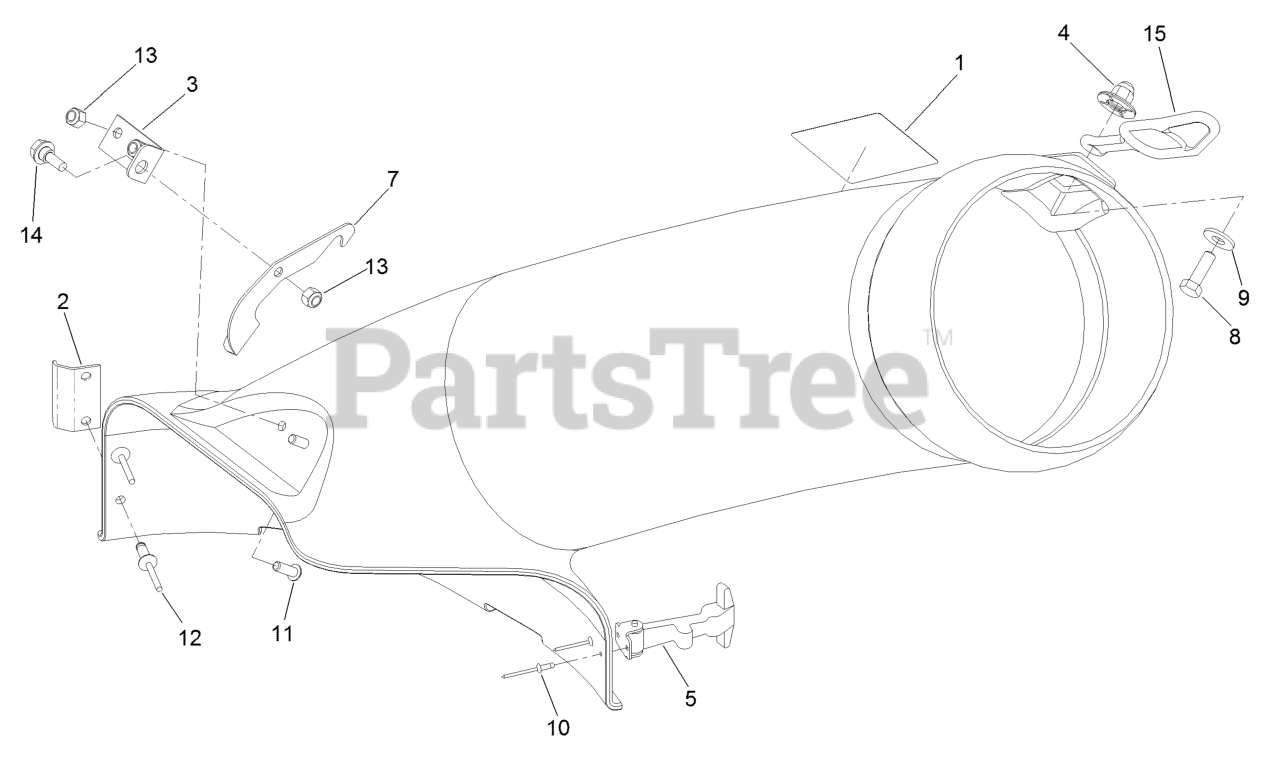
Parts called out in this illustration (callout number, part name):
1	DECAL-DANGER
2	BRACKET-ELBOW
3	PLATE-PIVOT
4	NUT-IMPELLER
5	HANDLE ASM
8	SCREW-HH
9	WASHER-FLAT
10	RIVET-POP
11	SCREW-HSBH
12	RIVET-BLIND
13	NUT-LOCK, NI
14	SCREW-SHOULDER,HWH
15	RETAINER-DUCT
